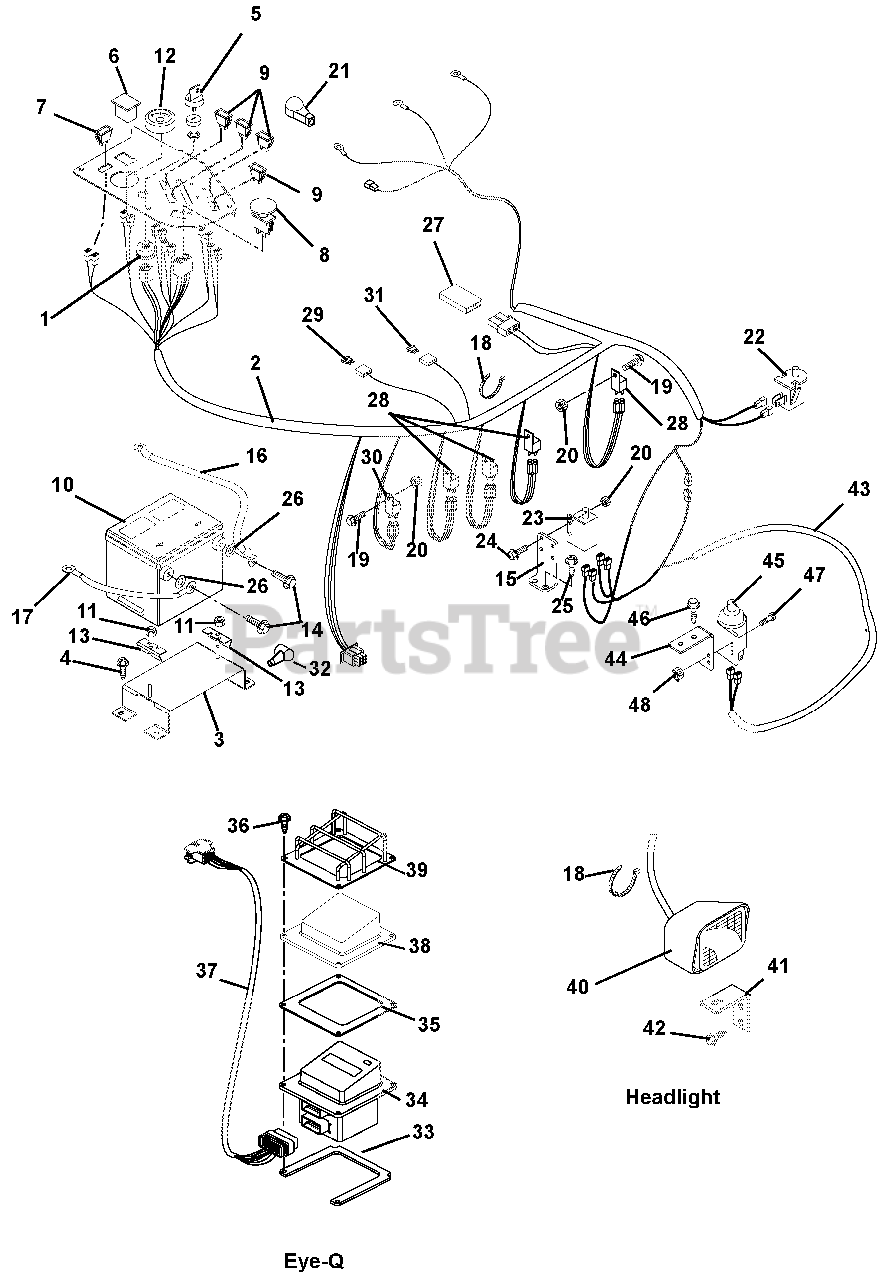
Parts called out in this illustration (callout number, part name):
1	SWITCH, IGNITION
2	HARNESS, MZ HORIZ L/C DIESEL
3	WMT, BATTERY SUPPORT
4	@SCR-TAP .38-16X.75 HWH TR YWZ
5	KEY, W/ SHIELD
5	IGNITION KEY SET
6	HOUR METER - DIGITAL
7	SWITCH, 2 POLE/ROCKER
8	SWITCH, CLUTCH
9	LIGHT,INDICATOR
10	BATTERY, GROUP 70 450 CCA 35 A
11	@NUT-LK-TOP-FLG .31-18 YWZC
12	GAUGE, TEMPERATURE
13	BRKT, BATTERY HOLD-DOWN
14	BATT TERMINAL SCREW
15	MOUNT, SAFETY SWITCH
16	CABLE-POS BATT W/BOOTS 4 X 48
17	CABLE, NEGATIVE BATTERY 49.00
18	CABLE TIE LG 5-1/2
19	@SCR-MCH 10-24X.75 HWH YWZC
20	@NUT-LK-NYL 10-24 W/INSRT YWZC
21	BOOT, TERMINAL, RED
22	SWITCH- SNAP MTG N.O.
23	SWITCH- DOUBLE POLE N.O./N.O.
24	@SCR-MCH 10-24X.75 HWH YWZC
25	@SCR-TAP .25-20X.50 HWH TR YWZ
26	@WSHR-FL-STL.38X.875X.083 YWZC
27	DIODE, CONNECTOR SHELL
28	RELAY,SEALED W/DIODE
29	FUSE, ATO 30 AMP
30	Pre-Heat Timer
31	FUSE, ATO 60 AMP
32	BOOT, BATTERY TERMINAL-RED
33	SPACER, ENCLOSURE MTG. (BTM)
34	EYE Q ENHANCED
35	GASKET-EYE Q
36	SCR-MCH 10-24X1.0 SL PAN BLACK
37	HARNESS, EYE-Q
38	GUARD, ELEMENT
39	WMT, EYE-Q GUARD
40	HEADLIGHT
41	BRACKET, HEADLIGHT MTG
42	@SCR-TAP .38-16X.50 HWH TR YWZ
43	HARNESS, WIRE ADAPTER CE
44	MOUNT - SWITCH
45	SWITCH-SINGLE POLE N.O.W/COVER
46	@SCR-TAP .31-18X.50 HWH TR YWZ
47	@SCR-MCH 10-24X.75 HWH YWZC
48	@NUT-LK-NYL 10-24 W/INSRT YWZC
